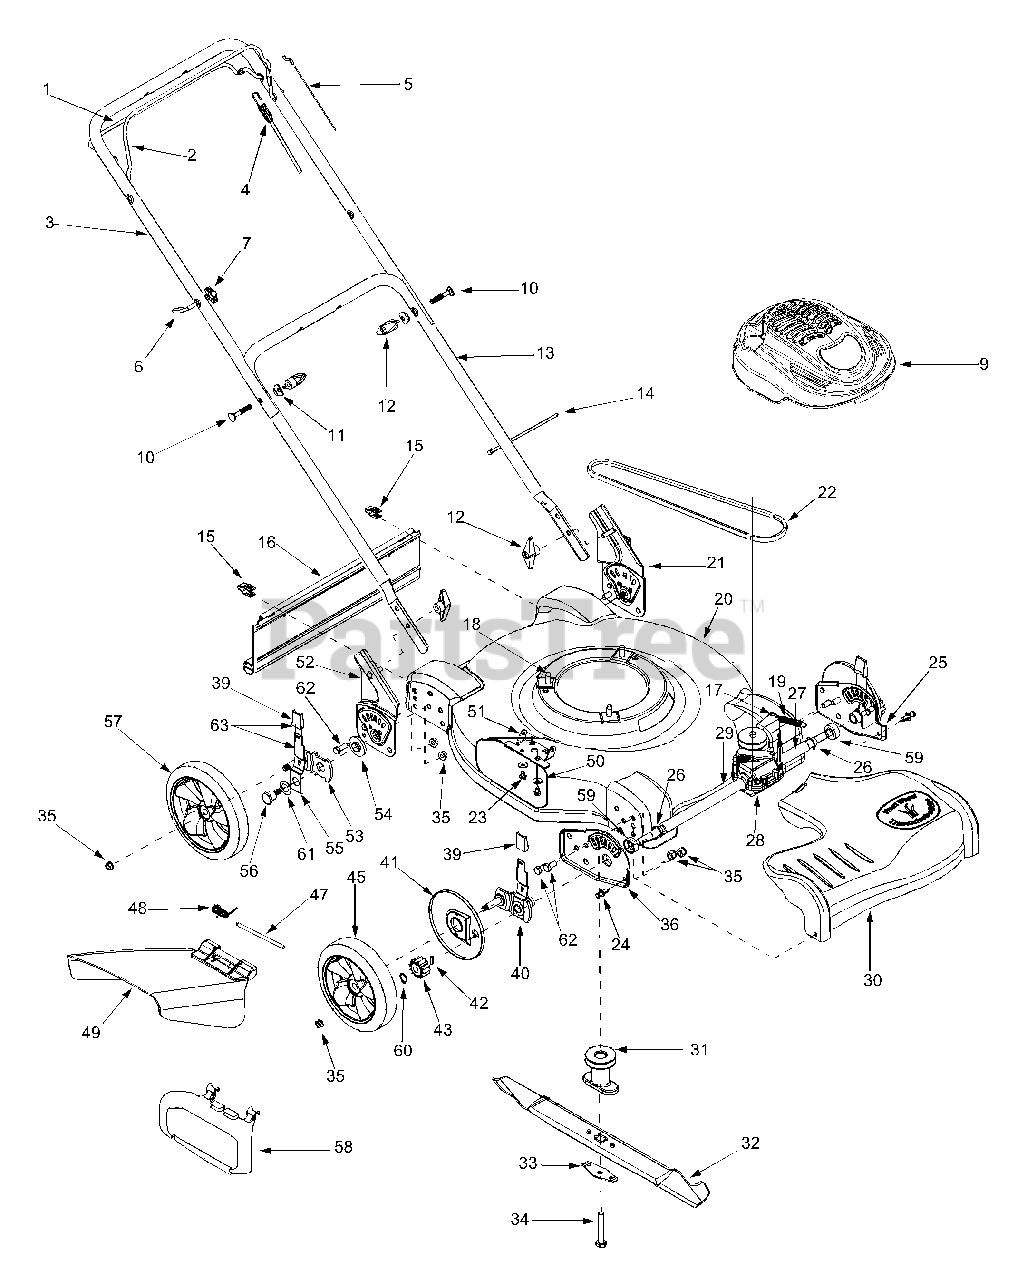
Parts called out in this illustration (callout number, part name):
1	Drive Control Handle
4	Drive Control Cable
5	Blade Control Cable 50.56" Lg.
6	Rope Guide Bolt
7	Knob - ERS Guide 1/4-20
9	Engine Shroud
10	Carriage Bolt 5/16-18 x 2.0
11	Saddle Washer .320 ID x .93 OD x .06
12	Wing Nut
14	Cable Tie
15	Hinge Clip
16	Trail Shield
17	Screw
18	Hex Wash HD Tap Scr 3/8-16 x .88
19	Spring .47 OD x 2.5
20	Deck Ass'y
22	V-Belt
23	Hex Wash S-Tapp Scr 1/4-20 x .50
24	Plastic Rivet
26	Retainer Ring
27	Sleeve Spacer .550 ID x 3.30 OD
28	Transmission Assembly Complete
29	Sleeve Spacer .550 ID x 7.95 OD
30	Transmission Cover
31	Blade Adapter
32	Mulching Blade 22"
33	Bell Blade Support
34	Hex Bolt 3/8-24 x 1.5" Lg. (Grade 8)
35	Flanged Lock Nut
39	Knob
40	Spring Lever Assembly (LH)
41	Dust Wheel Cover
42	Pin
43	Spur Gear 14T RH
45	Wheel Ass'y Comp. 8 x 1.8 Spoke Bar
47	Hinge Pin
48	Torsion Spring
49	Side Discharge Assembly
50	Cupped Washer .25 ID x .88 OD X .062
51	Chute Adapter
54	Height Adjuster Bearing
55	Spring Lever
56	Shoulder Screw 3/8-16
57	Wheel Ass'y Comp. 8 x 1.8
58	Snap Mulching Plug
59	Bearing Spacer
60	Snap Ring
61	Cupped Washer .401 ID x .870 OD
62	Hex Cap Screw 3/8-16 x .75
63	Spring Lever Ass'y
